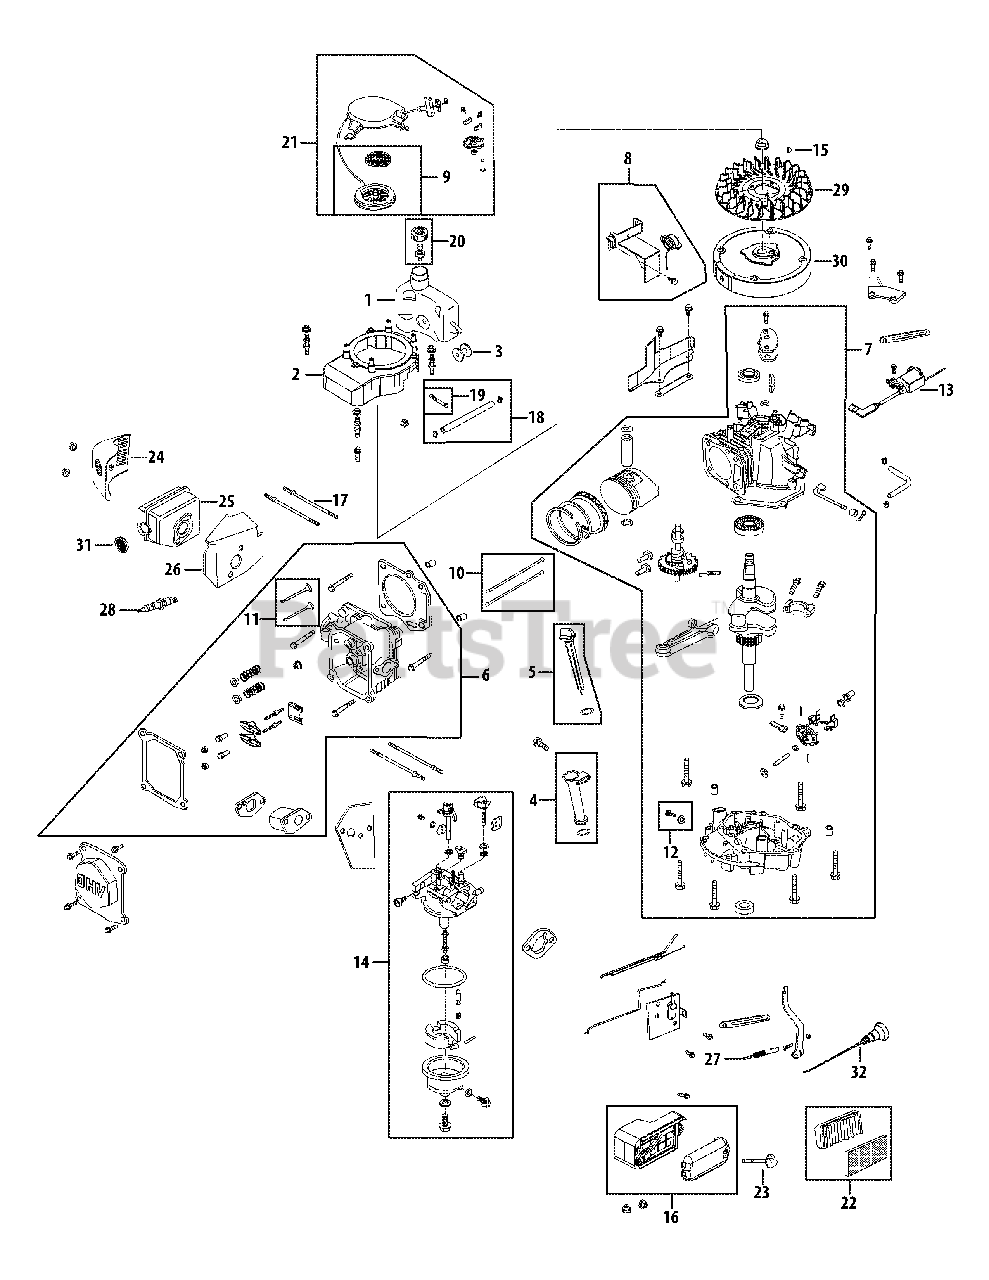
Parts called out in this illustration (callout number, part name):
1	Fuel Tank
2	Flywheel Shroud
3	Rubber Fuel Tank Mounting Washer
4	Oil Filler Tube Assembly
5	Dipstick Assembly
6	Cylinder Head Complete
7	Short Block Assembly
8	On/Off Switch and Bracket Assembly
9	Recoil Spring and Pulley Assembly
10	Push Rod Kit
11	Valve Kit
12	Oil Drain Plug and Washer Assembly
13	Ignition Coil
14	Carburetor Assembly
15	Flywheel Key
16	Air Cleaner Housing Assembly Complete
17	Muffler Stud Assembly
18	Fuel Line Kit
19	Fuel Filter
20	Fuel Cap Assembly
21	Recoil Starter Assembly
22	Air Cleaner Kit
23	Air Cleaner Thumb Screw
24	Muffler Guard
25	Muffler
26	Muffler Gasket /Heat Shield
27	Governor Return Spring
28	Spark Plug
29	Cooling Fan
30	Flywheel
31	Spark Arrestor
32	Choke Control Knob
